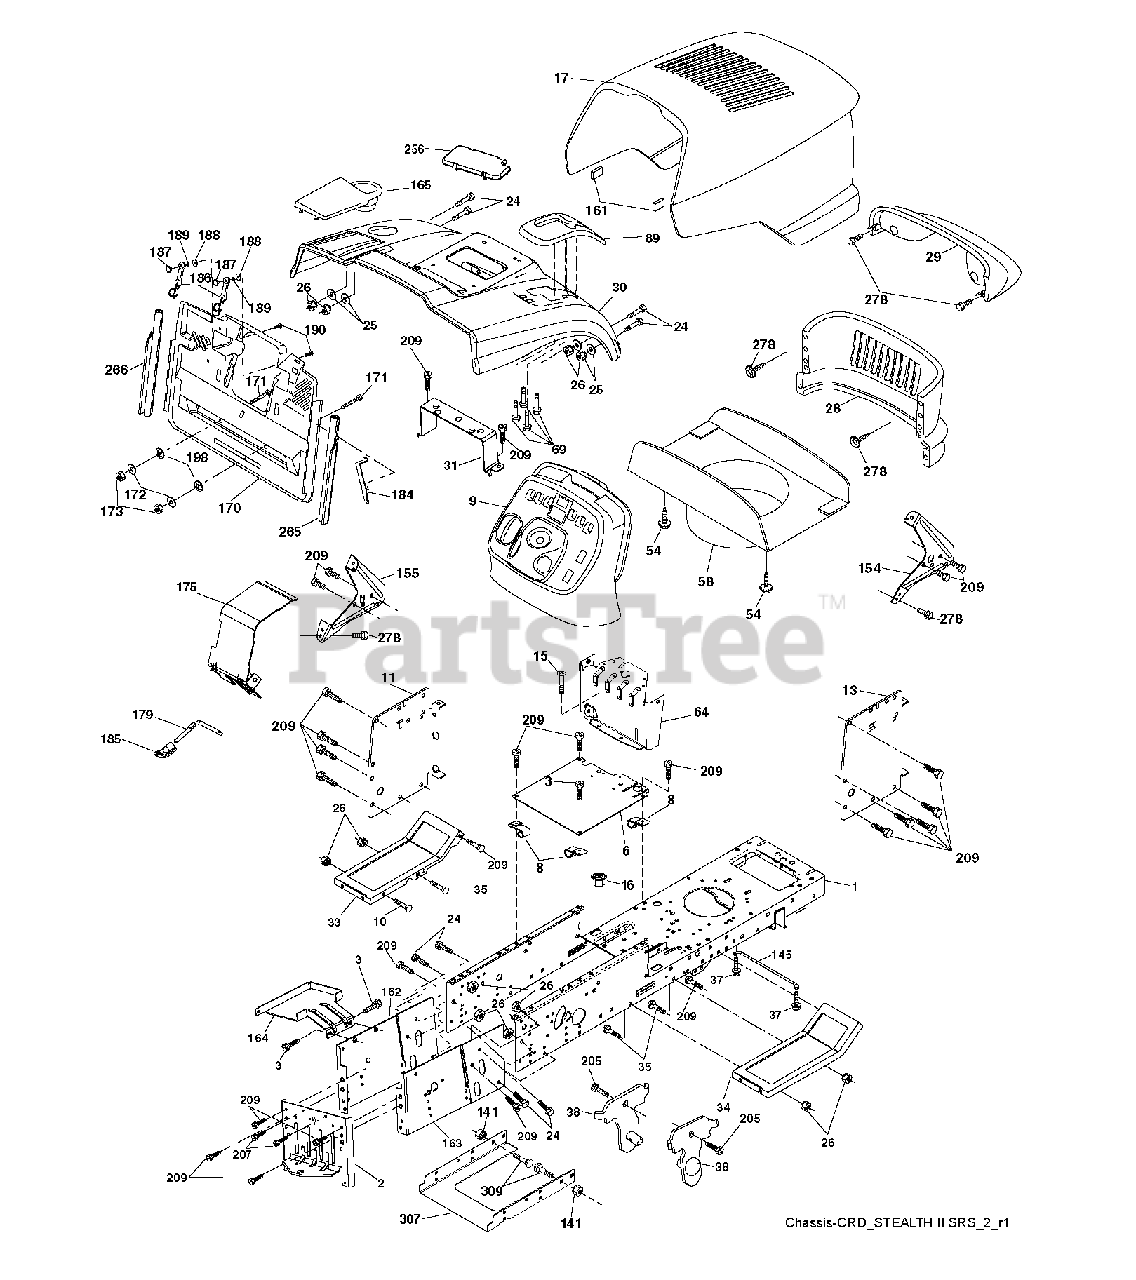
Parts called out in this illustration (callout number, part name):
1	CHASSIS
3	SCREW 3/8-16X3/4
8	CLIP,INSULATOR
10	BOLT D
13	PANEL DASH RH
16	NUT
25	WASHER
26	NUT
31	BRACKET SUPPORT FENDER
54	SCREW.WSHD.HEX10-32X5/8
58	DUCT HOOD
69	SCREW.HI-LO.CONSOLE
141	NUT LOCK FLG 3/8-16 UNC
145	ROD.PIVOT.HOOD
161	EXTRUSION BUMPER
164	SUPPORT
171	BOLT
172	WASHER
186	LATCH ASSY
187	WELDNUT
189	LOCKWASHER
207	SCREW, 5/16-18 X 1/2
209	SCREW, 3/8-16X3/4
278	SCREW.#10 X 0.750.BOS THREAD
